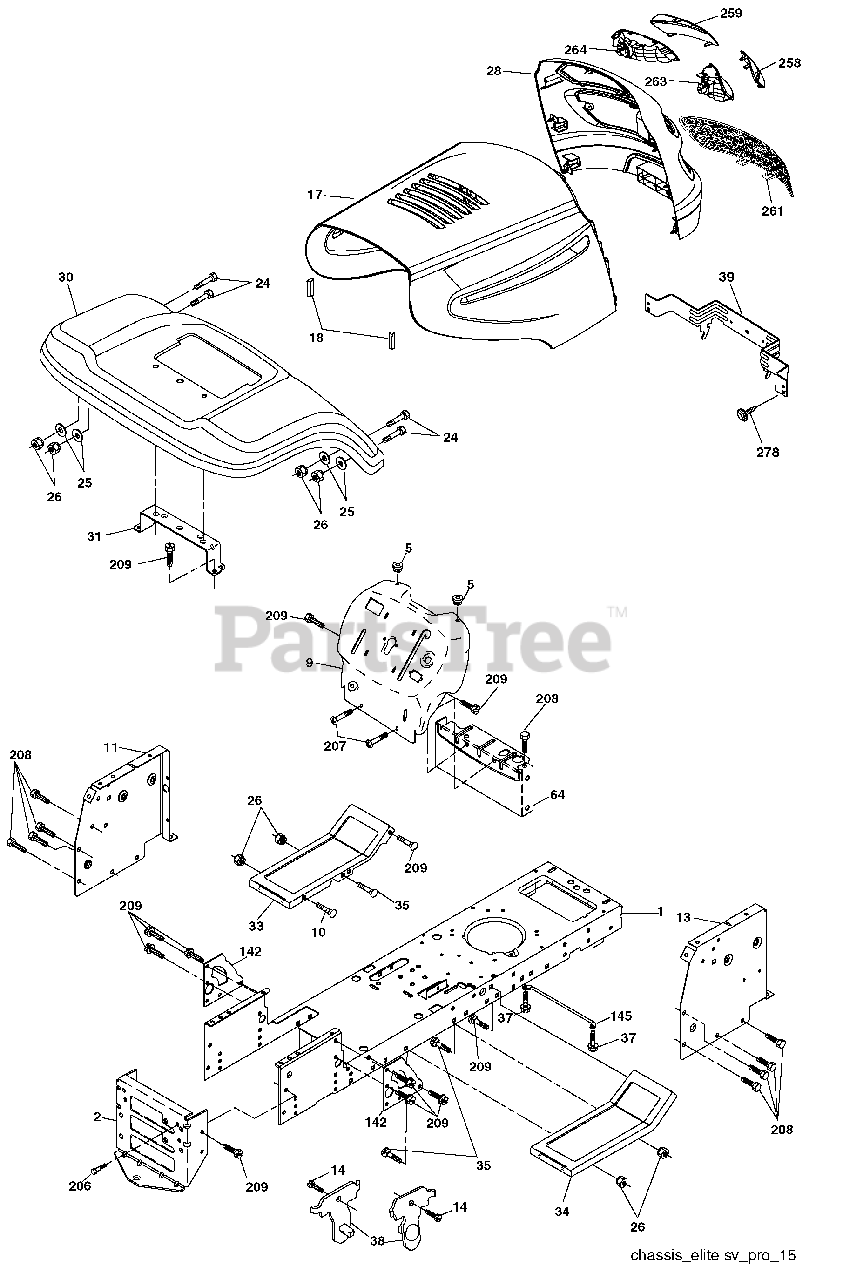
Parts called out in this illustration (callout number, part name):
1	Chassis
2	Drawbar
5	Bumper Hood/Dash
9	Dash
10	Bolt Carriage 3/8-16 x 1
11	Panel Dash Lh
14	Screw Thdrol 3/8-16 x 1-1/4
17	Hood
18	Bumper Hood
24	Bolt Fin Hex 3/8-16 x 1 Gr. 5
25	Washer 13/32 x 13/16 x 12 Ga.
26	Nut Lock Hex W/Ins 3/8-16 unc
28	Grille Asm
30	Fender Footrest STLT Pnt
31	Bracket Support Fender
33	Footrest Pnt Lh
34	Footrest Pnt Rh
35	Bolt Rdhd Sht Sqnk 3/8-16 x 3/4
37	Screw Thdrol 6/16-18 x 1/2 TYT
38	Bracket Asm. Pivot Mower Rear
39	Bracket Pivot
64	Dash Lower STLT
142	Plate Reinforcement STLT
145	Rod Pivot Chassis/Hood
206	Bolt Shoulder 5/16-18
207	Screw Thdrol 5/16-18 x 1/2
208	Screw Thdrol 3/8-16 x 1/2
209	Screw Hex Wsh Thdr. 3/8-16 x 3/4
258	Lens RH
259	Lens LH
263	Bezel RH
264	Bezel LH
278	Screw 10 x 3/4 Single Lead-Hex
278	Plug Dome
278	Plug Btn Blk .359
